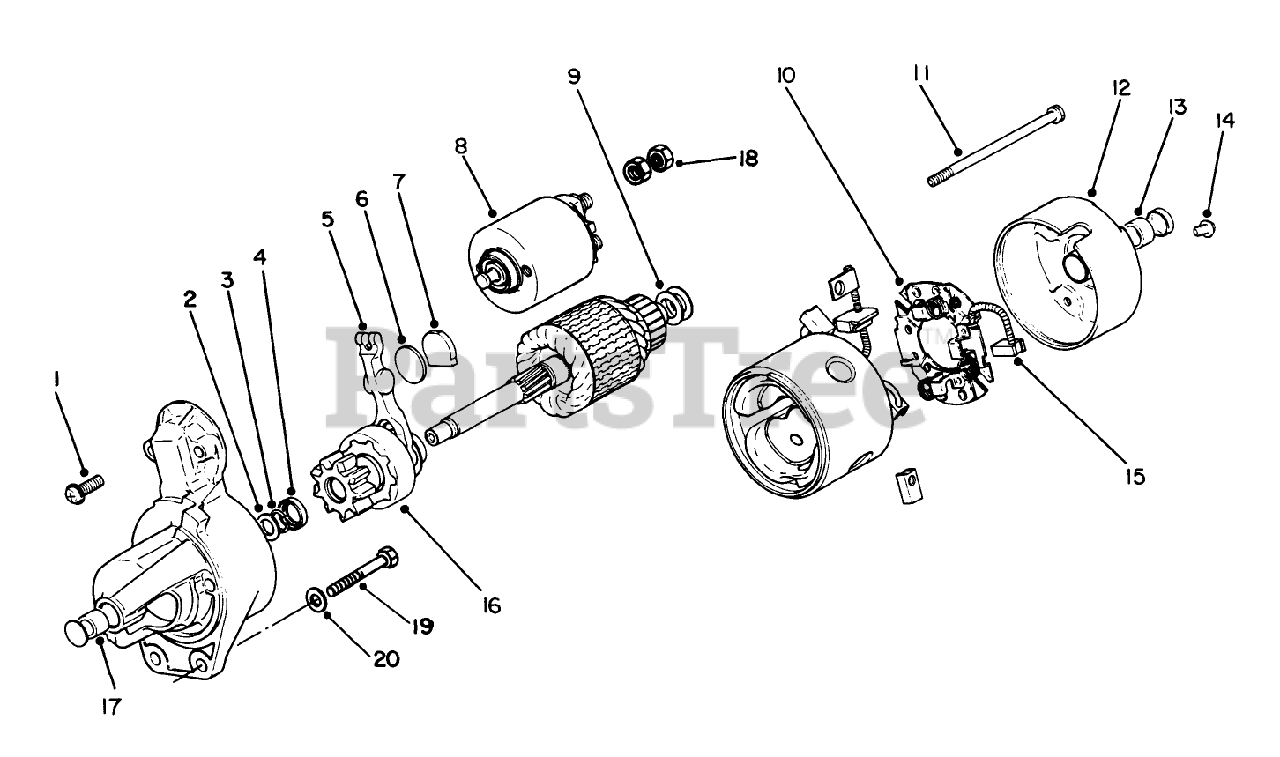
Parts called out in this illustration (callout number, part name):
1	Kit-Hardware (Incl. Item #2-4, 9, 11 & 14)
2	Washer
3	Ring-Pinion Retainer
4	Collar-Pinion Stop
5	Kit-Shift Lever (Incl. Item #6 & 7)
6	Plate-Wear
7	Plug-Rubber
8	STARTER SOLENOID KIT
9	Shim-Armature
10	Holder-Brush Assy. (Incl. in ea. brush)
11	Bolt
12	Kit-Bushing (Incl. Item #13)
14	Screw-Brush Holder
15	Kit-Brush (Incl. 2 neg. & 1 pos. brushes)
16	Starter Clutch Assy.
17	BUSHING
18	NUT-JAM
19	SCREW-HH
20	TINE-HOLLOW, LW 5/8 X 4.75
